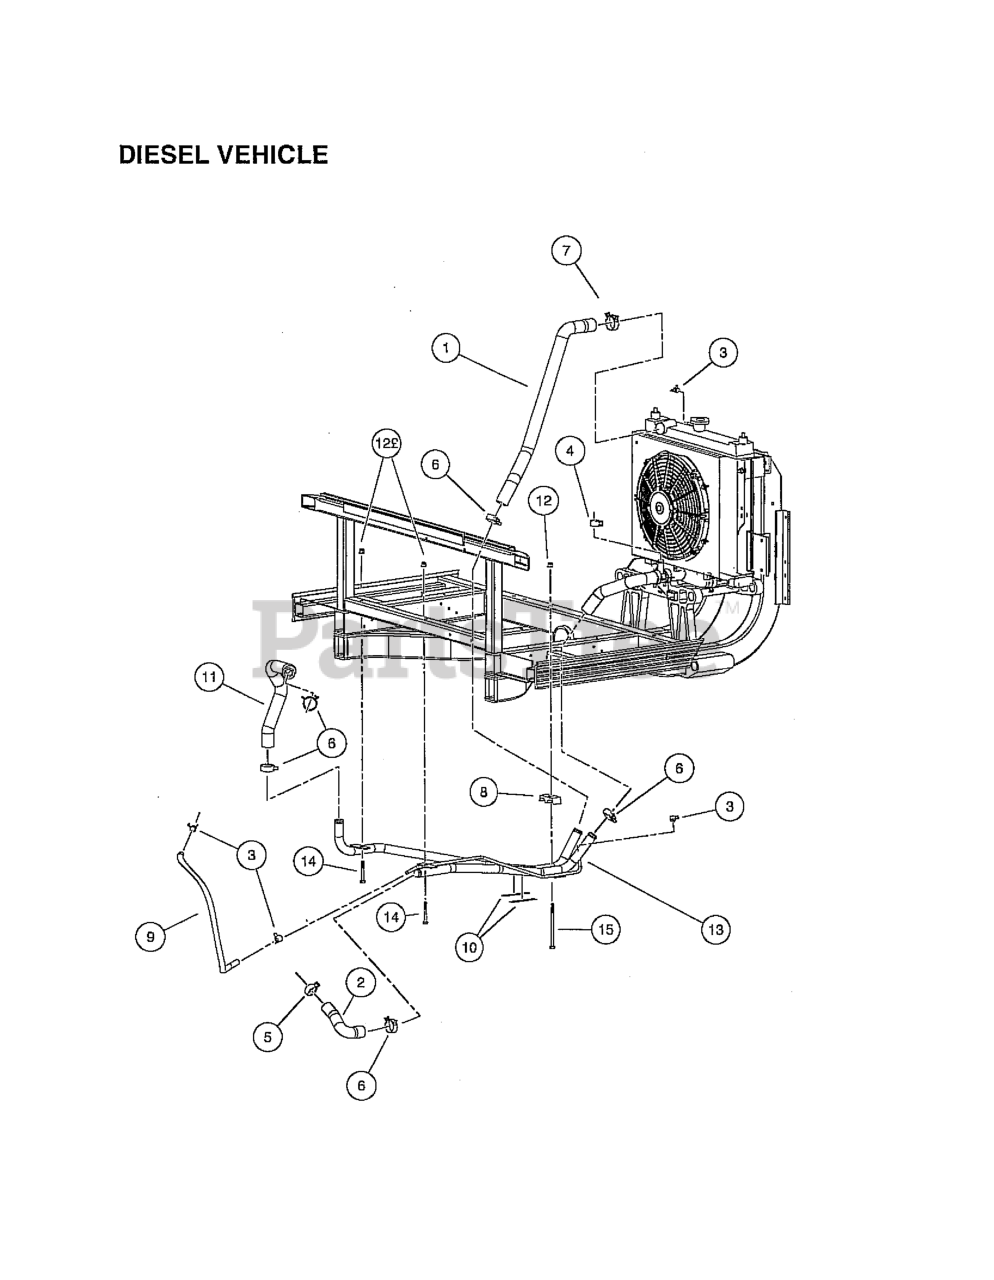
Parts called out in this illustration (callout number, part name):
1	HOSE, COOLANT UPPER RAD
2	HOSE, COOLANT LOWER ENG
3	CLAMP, HOSE, CTB 15MM
4	CLAMP, HOSE, CTB 22MM
5	CLAMP, HOSE, CTB 30MM
6	CLAMP, HOSE, CTB 35MM
7	CLAMP, HOSE, CTB 38MM
8	CLAMP, BAR
9	HOSE, VENT TUBE TO ENG, COOLNT
10	DECAL, WARNING HOT SURFACE
11	HOSE, COOLANT, RETURN, ENGINE
12	LOCK NUT, FLG M8 X 1.25 NYLON
13	WELDMENT-GROUP-COOLANT PIPE
15	BOLT, M8 X 1.25 X 130
